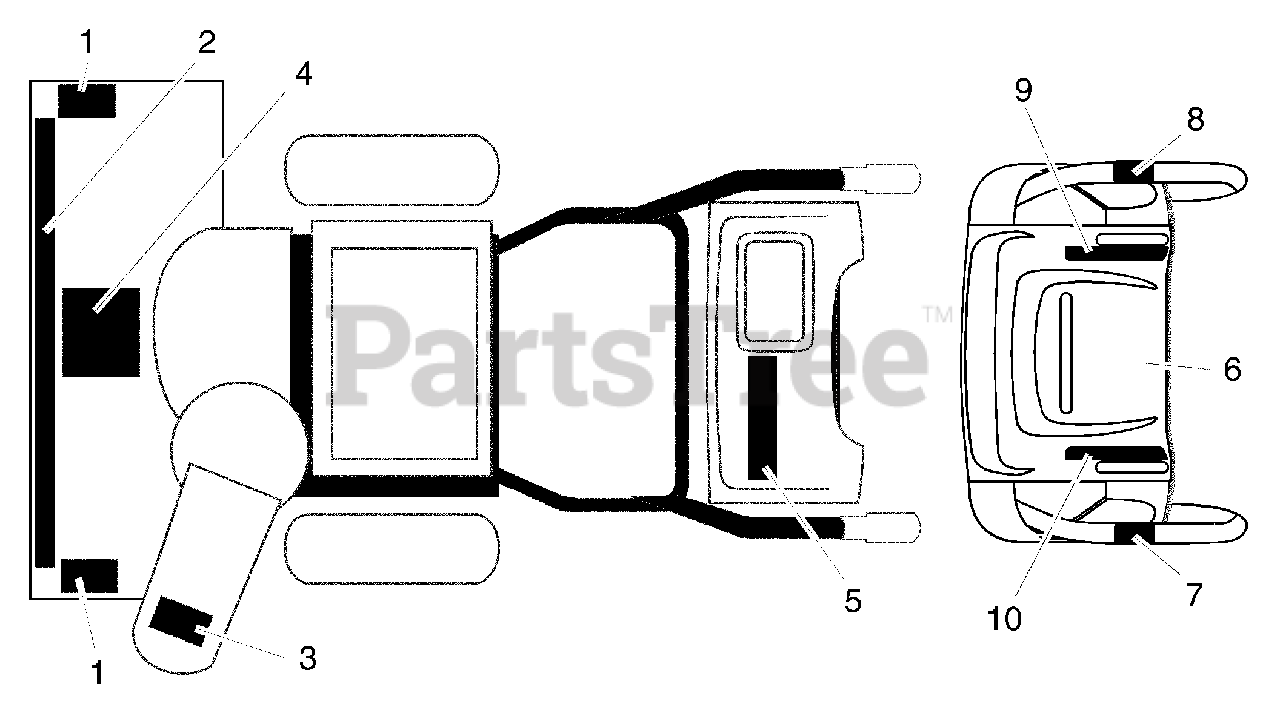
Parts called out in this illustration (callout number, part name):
1	Decal, Danger
2	Decal, Poulan Pro, 5.5HP/24" (large)
3	Decal, Danger, Deflector
4	Decal, Danger
5	Decal, Poulan Pro, 5.5HP/24" (small)
6	Decal, Instruction
7	Decal, Traction Lever
8	Decal, Auger Lever
9	Decal, Speed Control
